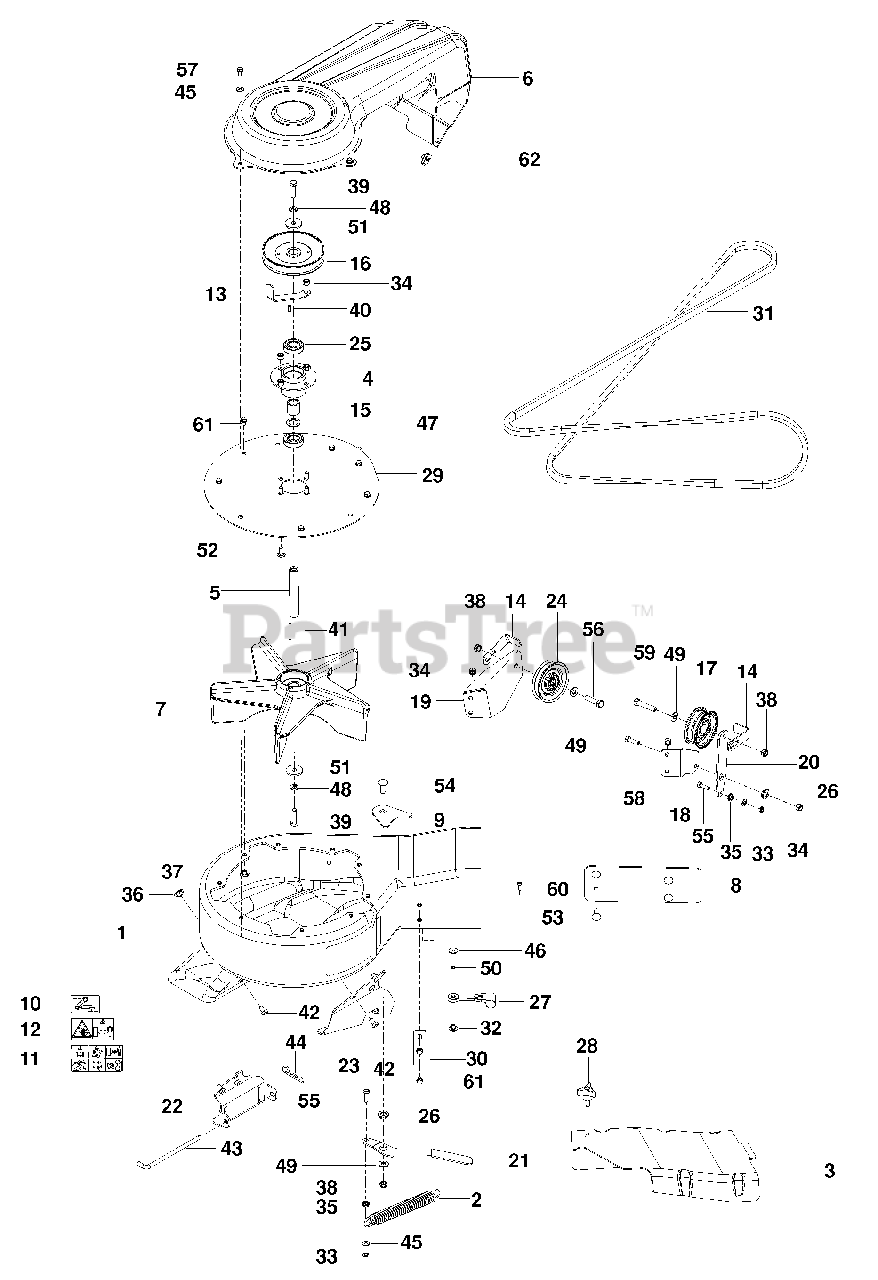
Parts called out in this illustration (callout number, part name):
1	Housing W/ Decals
2	Traction Spring
3	Cover, Belt
4	Hub, Bearing
5	Shaft, Impeller
6	Cover, Belt
8	Plate, Backing
9	Plate, Backing
10	Decal, Belt Routing
11	Decal, Warning
12	Decal, Severing
13	Keeper, Belt, Outer
14	Keeper, Belt, Rear
17	Pulley, Idler
18	Mount, Idler, Upper
19	Mount, Idler, Lower
20	Arm, Idler
21	Arm, Tension
22	Bracket, Mount, Front
23	Bracket, Mount, Rear
27	Latch, Hood
28	Knob W/ Stud
29	Plate, Outer
32	Weld Nut, Plated
33	Nut 1/4-20 Hex Nyloc
34	Nut 5/16-18 Hex Nyloc
35	Nut 1/4-20 Hex Flange
36	Nut 5/16-18 Tee
37	Nut 1/4-20 Tee
38	Nut 3/8-16 Hex Jam Nyloc
39	Bolt, Hex 3/8-24 X 11/4 Gr
40	Key 3/16 X 11/2
41	Key 3/16 X 11/2
42	Hcs 5/16-18 X 1/2
44	Hairpin Cotter
45	Washer 1/4 Flat Sae
46	Washer, 3/16 X 3/4 X 16 Ga
48	Washer 3/8 Splt Lock
49	Washer 3/8 Sae Flt
50	Washer 3/16 Lock
51	Washer, Hardened
52	Rhsnb 5/16-18 X 3/4
53	Rhsnb 5/16-18 X 1
54	Rhsnb 3/8-16 X 1
55	Hcs 1/4-20 X 7/8
56	Hcs 3/8-16 X 1 1/2
57	Hcs 1/4-20 X 1/2
58	Hcs 5/16-18 X 1
59	Hcs 3/8-16 X 1 3/4
60	Screw 10-24 X .625 Rd
61	Screw 1/4 X 3/8 Thd Frm
62	Retainer, U Type
